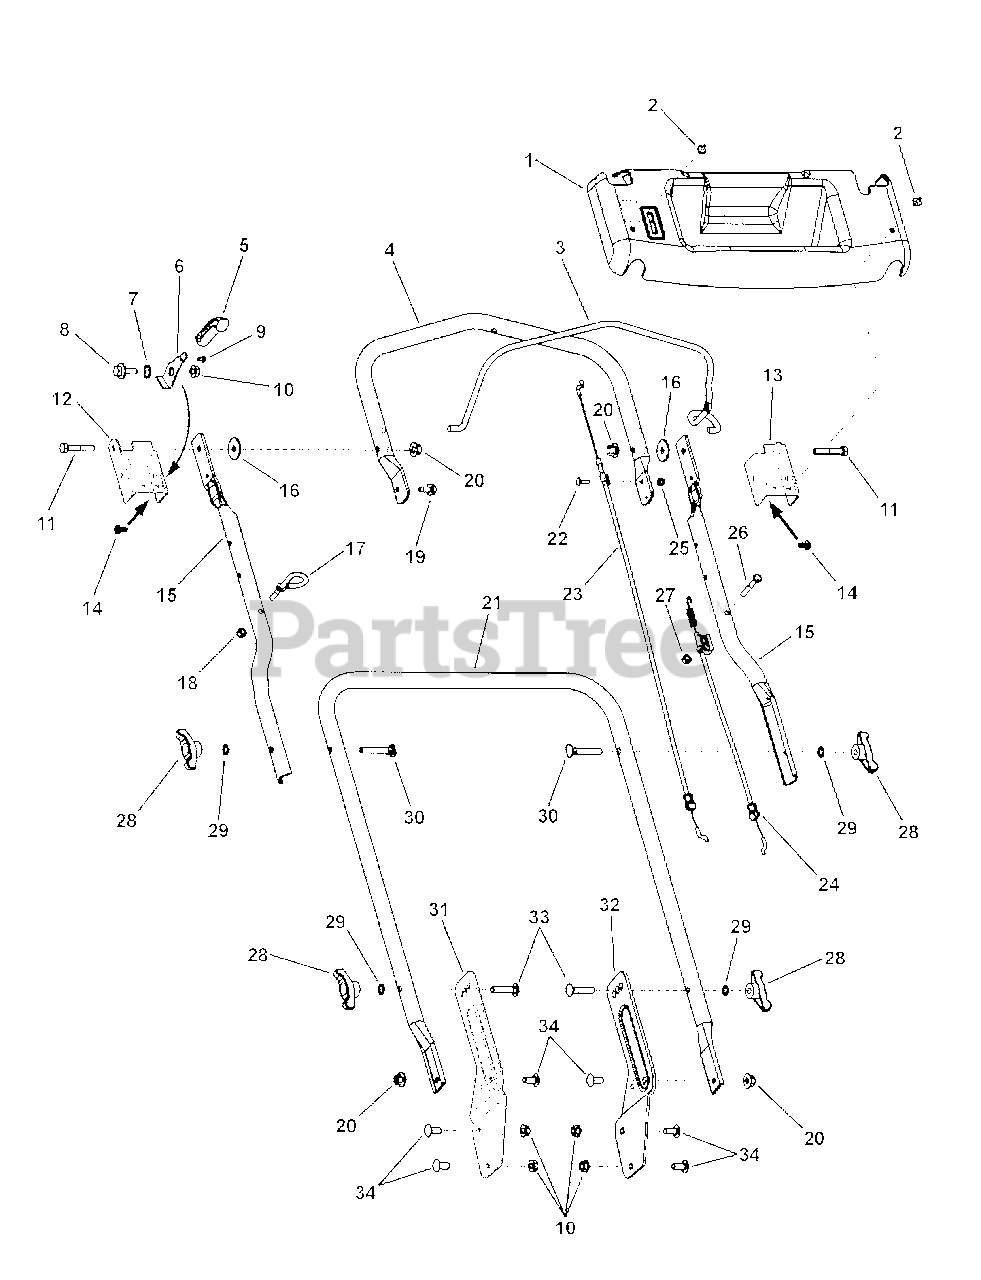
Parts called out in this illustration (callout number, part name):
1	PANEL, Upper Handle, Snapper 21 WBM
2	POP RIVET, .250 Dia.
3	BAIL, Pivot Handle
4	HANDLE, Pivot
5	LEVER, Lock Handle
6	HANDLE, Lock
7	WASHER, .531 x .781 Wave
8	BOLT, 5/16-18 Shoulder
9	RIVET, Plastic Snap
10	NUT, 5/16-18 Flange Lock, YZ
11	SCREW, 5/16-18 x 1-3/4" Hex Head Cap, GR 5
12	BRACKET, Rotation Limit, RH
13	BRACKET, Rotation Limit, LH
14	SCREW, 1/4-20 x .55 Torx Self-Tap
15	HANDLE, Upper, Pivot, 21"
16	WASHER, 5/16 Nylon
17	ROPE GUIDE, (1/4-20 thread)
18	NUT, 1/4-20 Hex Nyloc
19	SCREW, 5/16-18 x 5/8" Hex Washer Self-Tap
20	NUT, 5/16-18 Large Head Center Lock, Black
21	HANDLE, Lower
22	BOLT, #10-24 x 1/2" Flat Head Square Neck
23	CABLE, OPC, Pivot Handle
24	CABLE, Drive
25	NUT, #10-24 Hex Nyloc
26	SCREW, 1/4-20 x 1-3/4, Hex Head Cap, GR 5
27	NUT, 1/4-20 Hex Center Lock
28	KNOB, 5/16-18 Wing (Black)
29	WASHER, 5/16" Internal Tooth Lock
30	BOLT, 5/16-18 x 2" Curved Head Square Neck, GR 2
31	BRACKET, Lower Handle RH 21" WBM
32	BRACKET, Lower Handle, LH 21" WBM
33	BOLT, 5/16-18 x 1-1/2" Round Head Square Neck
34	BOLT, 5/16-18 x 3/4" Round Head Short Square Neck, GR5 YZ
